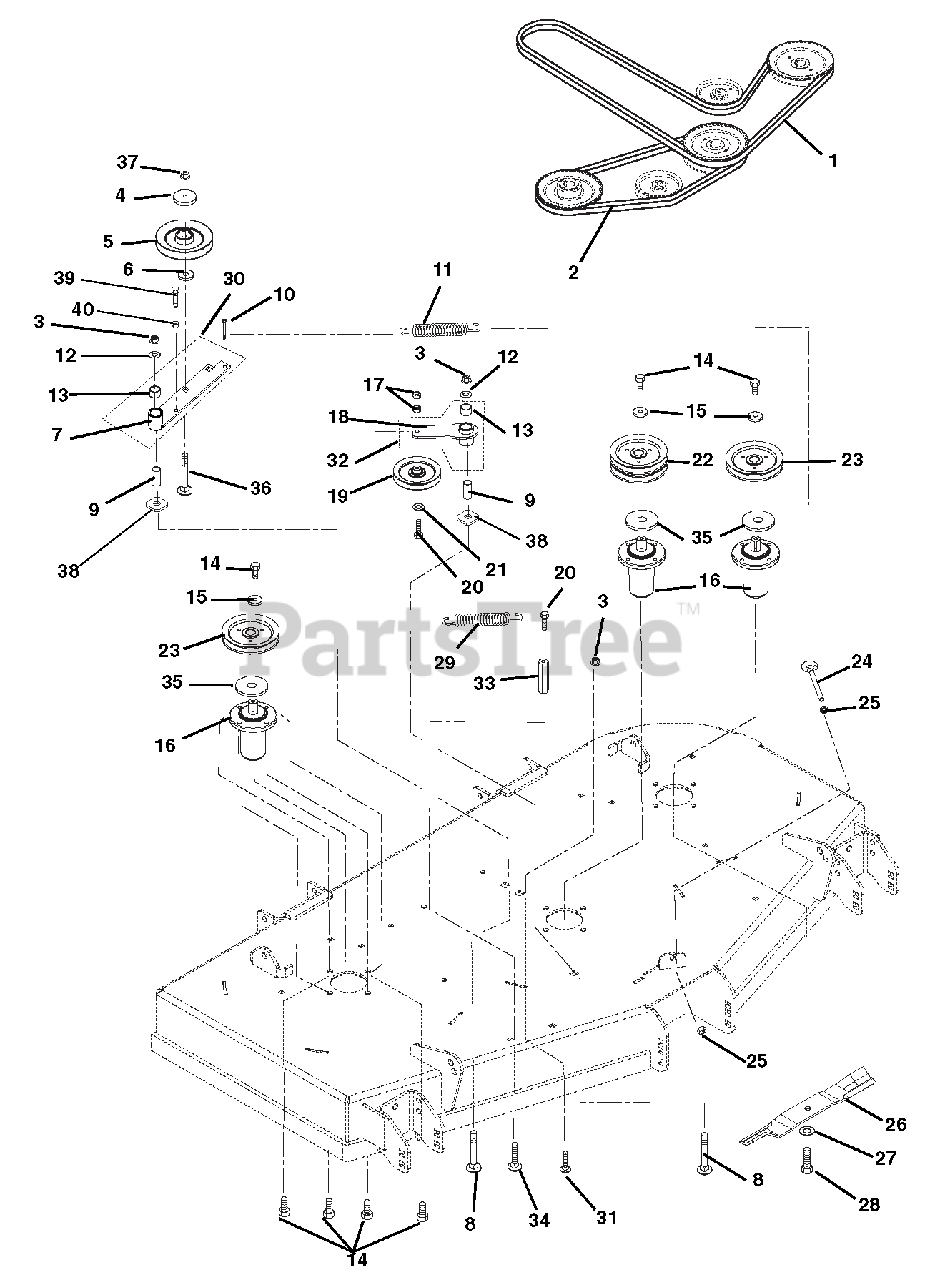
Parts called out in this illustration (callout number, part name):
1	HEX BELT, BB-WRAPPED
2	V-BELT, B-COGGED
3	@NUT-LK-NYL-FLG .50-13 YWZC
4	CAP, IDLER BEARING SEALING
5	SHV, .50"ID X 6.00"OD V-IDLER
6	BSHG, SPCR .502X.997X.50 PM
7	WMT, IDLER ARM
8	@BLT-RDHDSQNK .50-13X3.50 G5YZ
9	BSHG, SPCR .502X.997X2.03 PM
10	BLT,SHLDR EP .38-16X.30 HEX YZ
11	SPRING, EXTENSION
12	@WSHR-FL-STL.563X1.38X.109YWZC
13	BSHG, 1.00 X 1.125 X 1.937
14	BLT-HEX .38-16X1.0 GR8 YZ EP30
15	WSHR,FLT STL.406X1.50X.245YWZC
16	ASSEMBLY, SPINDLE
16	ASSEMBLY, SPINDLE-LONG G3500
17	@NUT-LK-CTR .38-16 YWZC
18	WMT, IDLER ARM - BLACK
19	SHV, .38"ID X 5.00"OD V-IDLER
20	@BLT-HEX .38-16X2.25 GR5 YWZC
21	@WSHR-FL-STL.406X.812X.065 YWZ
22	SHEAVE, DOUBLE 1"ID X 6.00"OD
22	PULLEY, DOUBLE-1"ID X 6.75"OD
22	SHEAVE, DOUBLE 1"ID X 8.25"OD
23	SHEAVE, SINGLE 1"ID X 6.00" OD
23	PULLEY, V-1" ID X 6.75" OD
23	SHEAVE, SINGLE 1"ID X 8.25"OD
24	BOLT, .38-16X4.50 .62 DIA EYE
25	NUT-HEX-JAM .375-16 YWZC
26	BLADE, MULCH 18.00"
26	BLADE, MULCHING (20.50")
26	BLADE,MOWER-72"MULCH(24.5"LG)
27	WSHR-BLVL .669X1.535X.138
28	BLT-HEX .62-18X1.75 GR8 YWZC
29	SPRING, EXTENSION
30	ASM, IDLER PIVOT ARM (PTO)
31	BLT-RDHDSHSQNKFT.50-13X1.50 G5
32	ASM, IDLER ARM (DECK)
33	NUT COUPLING .375-16X1.75
34	@BLT-RDHDSHSQNK.38-16X1.0 G5YZ
35	RETAINER, GREASE
36	@BLT-RDHDSQNK .50-13X3.00 G5YZ
37	@NUT-LK-CTR .50-13 YWZC
38	WSHR-FLT .640X1.75X.250
39	@BLT-HEX .38-16X2.75 GR5 YWZC
40	@NUT-HEX .38-16 YWZC
